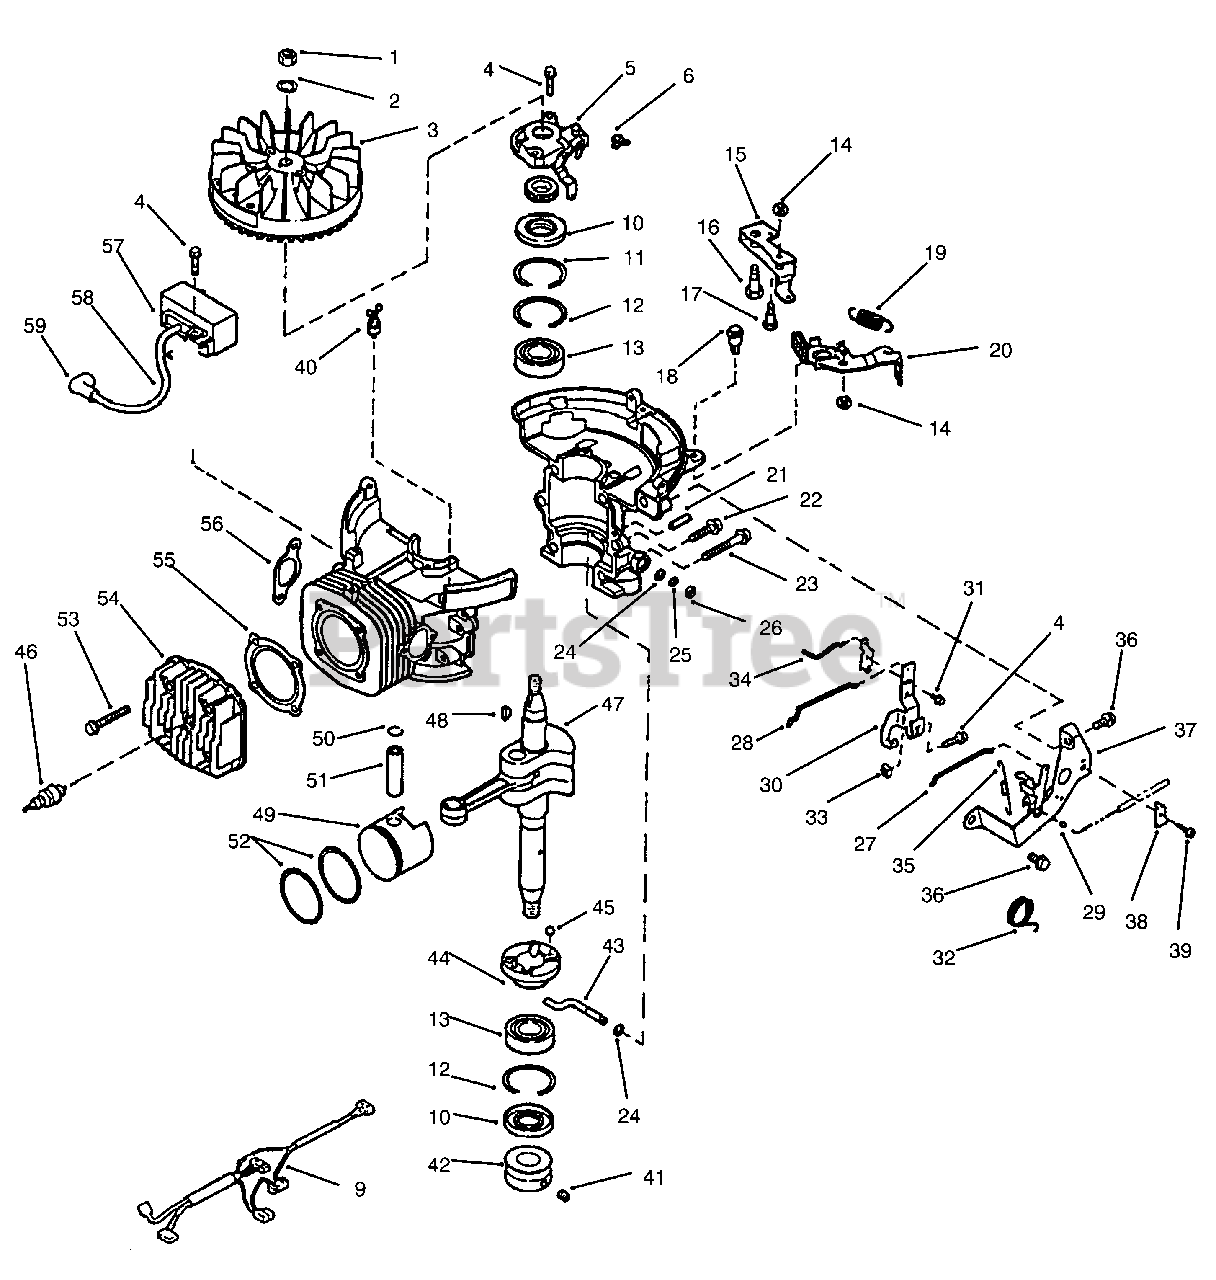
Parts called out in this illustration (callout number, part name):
1	Nut Flywheel
2	Lockwasher
3	Flywheel (Model No. 10590)
3	Flywheel (Model No. 10591)
5	Oil Pump Kit w/Oil Lines (Incl. Ref. No. 6)
6	Clamp-Oil Line
9	Wire Harness (10591)
9	Wire Harness (10590)
10	Oil Seal-Crankshaft
11	Ring-Retaining
12	Ring-Retaining
13	Bearing-Crankshaft
14	Nut (Model No. 10590)
15	Brake Actuator (Model No. 10590)
16	Shoulder Bolt (Model No. 10591)
16	Shoulder Bolt (Model No. 10590)
17	Shoulder Bolt (Model No. 10590)
18	Shoulder Bolt (Model No. 10590)
19	Brake Spring (Model No. 10590)
20	Brake & Switch (Model No.10590)
21	Pin-Taper
24	Washer-Governor Shaft
25	Ring-Retain.-Gov. Shaft
26	Seal-Oil, Govenor Shaft
27	Rod-Choke
28	Rod-Throttle
29	Retainer-Throttle Wire
30	Kit-Gov. & Oil Pump Lever (Incl. Ref. No. 31)
32	Spring-Torsion
34	Rod-Oil Pump Control
35	Spring-Governor
37	Assy.-Governor Bracket (Model No. 10590) (Incl. Ref. No. 32)
37	Assy.-Bracket & Switch (Model No.10591) (Incl. Ref. No. 32)
38	Clamp-Throttle Cable
40	Wire Tie (Model NO. 10591)
41	Screw-Set, Engine Pulley
42	Pulley-Engine
43	Shaft-Governor
44	Ramp-Governor
45	Ball-Governor
46	Spark Plug
47	Crankshaft & Conn. Rod (Model No. 10590)
47	Crankshaft & Conn. Rod (Model No. 10591)
48	Key (Model No. 10590)
48	Key (Model No. 10591)
49	Assy.-Piston & Ring (Std.) (Incl. Ref. No. 50-52)
49	Assy.-Piston & Ring (0.020" Oversize) (Inc 50-52)
50	Ring-Retaining
51	Pin-Wrist
52	Ring Set (Standard)
52	Ring Set (0.020" Oversize)
53	Screw-Cyl. Head to Block
54	Head-Cylinder
55	Gasket-Head
56	Gasket-Exhaust
57	Module-C.D. Ignition (Incl. Ref. No. 58-59)
58	High Tension Lead & Cover (Incl. Ref. No. 59)
59	Assy.-Cover & Terminal
